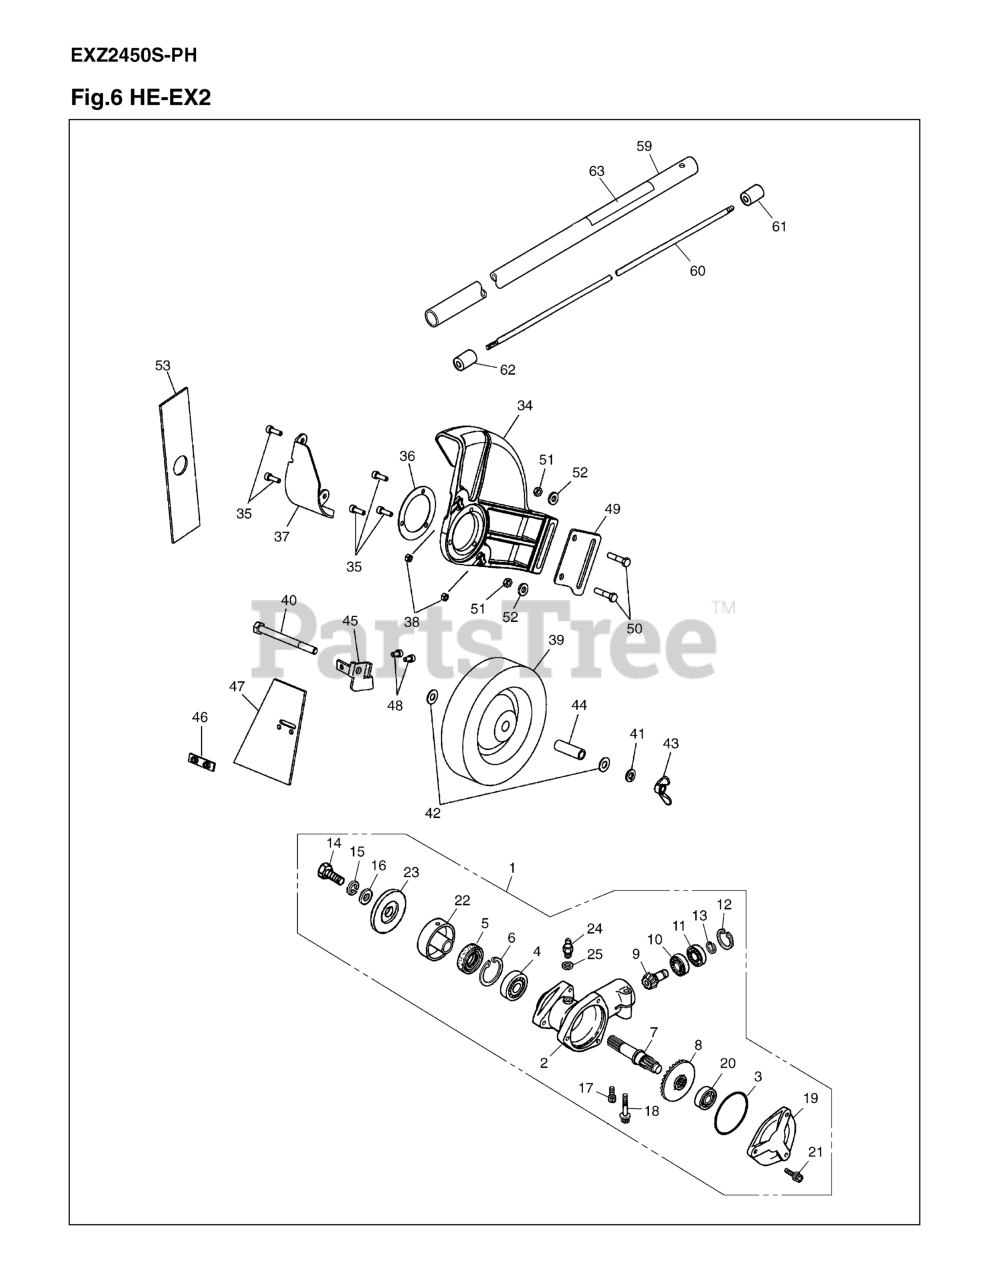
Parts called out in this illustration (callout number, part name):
1	GEARCASE ASSY
2	GEARCASE
3	O-RING
5	SEAL
6	SNAP RING
7	SHAFT
8	GEAR
9	PINION
10	BEARING
11	BEARING
12	SNAP RING
13	SNAP RING
14	BOLT
15	WASHER
16	WASHER
17	BOLT
18	BOLT
19	COVER
20	BEARING
21	BOLT
22	HOLDER (A)
23	HOLDER (B)
24	FITTING, GREASE
25	WASHER, FITTING
34	GUARD
35	BOLT
36	PLATE
37	PROTECTOR
38	NUT
39	WHEEL
40	BOLT
41	WASHER, SPRING
42	WASHER
44	SLEEVE
45	BRACKET
48	BOLT
49	Main Bracket
50	BOLT
51	NUT
52	WASHER
59	PIPE COMPLETE
60	SHAFT
61	JOINT, SHAFT (RPLS -12240)
62	SPACER
63	PLATE, NAME
